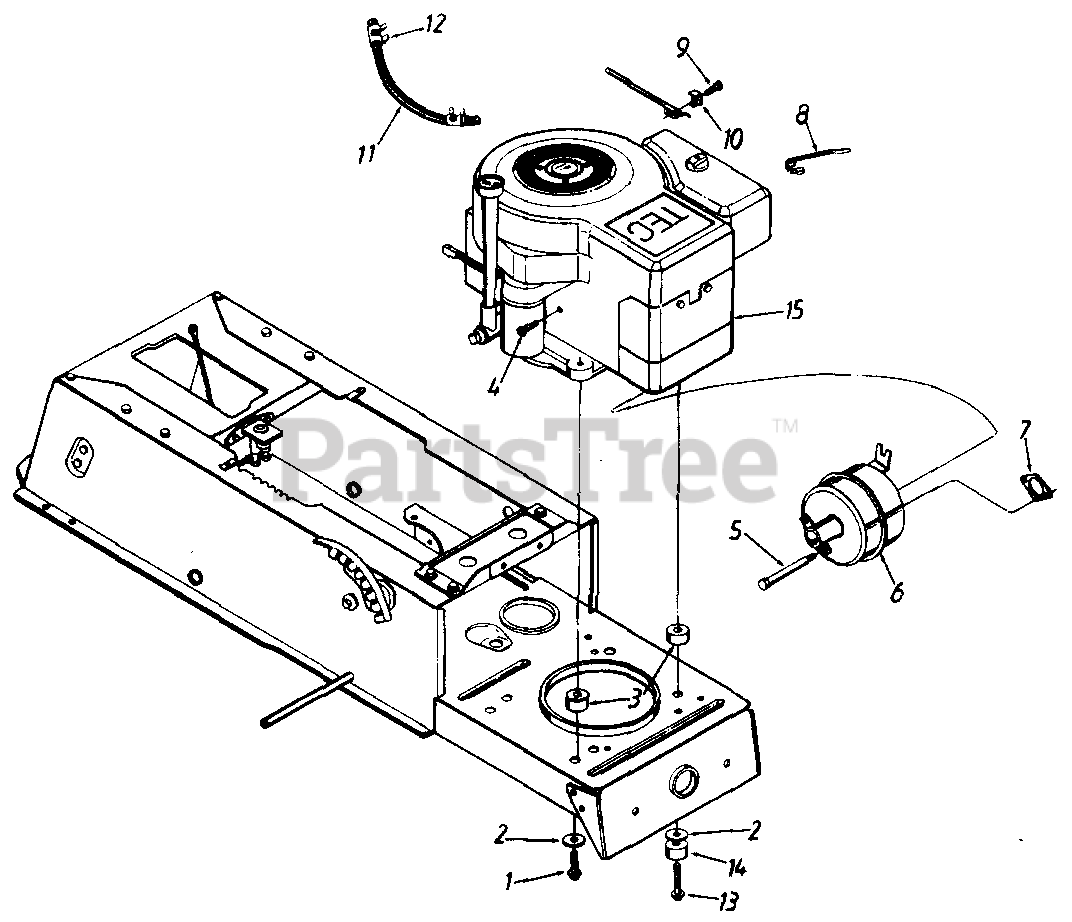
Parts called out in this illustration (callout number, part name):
1	Hex L-Wash. TT-Tap Scr. 3/8-16 x 1.5" Lg.
2	Fl-Wash. 3/8" I.D. x 1-1/4" O.D.
4	Pan Hd. Mach. Scr. 5/16-18 x .75" Lg.
5	Shld. Bolt 7/16" Dia. x 3-5/8" Lg. 12 & 12.5 H.P. Only
6	Muffler 12 & 12.5 H.P. Only
7	Exhaust Gasket 12 & 12.5 H.P. Only
8	Cable Tie
9	Hex Sems Scr. #10-32 x 5/8" Lg.
10	Casing Clamp
11	Fuel Line
12	Hose Clamp
13	Hex L-Wash. TT-Tap Scr. 3/8-16 x 2.5" Lg. 16 H.P. Only
14	Shld. Spacer .38" I.D. x 1.25" O.D. 16 H.P. Only
15	Engine
